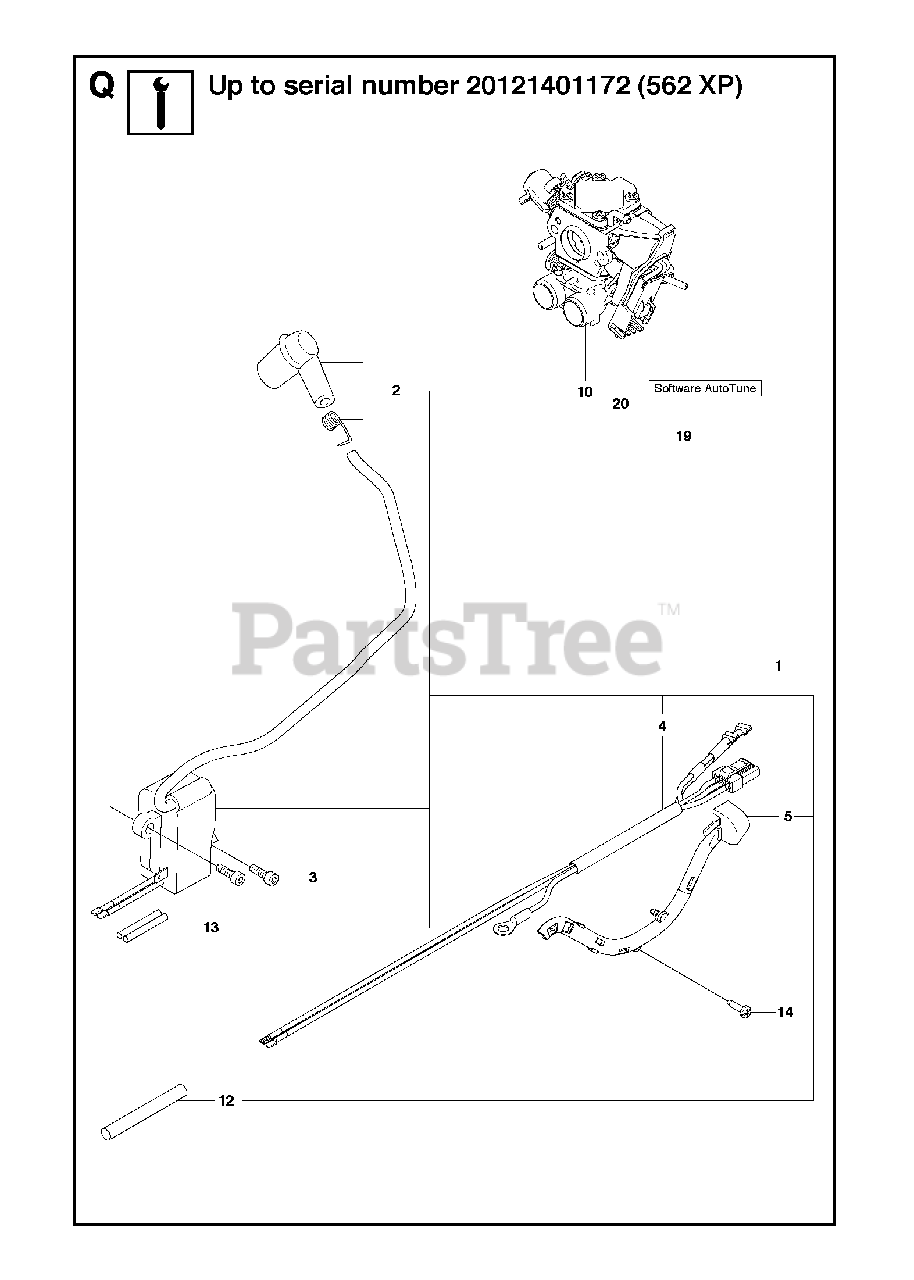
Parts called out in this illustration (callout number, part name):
1	RP IGNITION MODULE ASSY
2	SPARK PLUG CAP ASSY
4	WIRING ASSY
5	CABLE HOLDER
10	CARBURETOR KIT 555 AUTOTUNE
12	CABLE COVER
13	SHRINK HOSE
19	Husqvarna TBD
20	SPARE PARTS KIT
